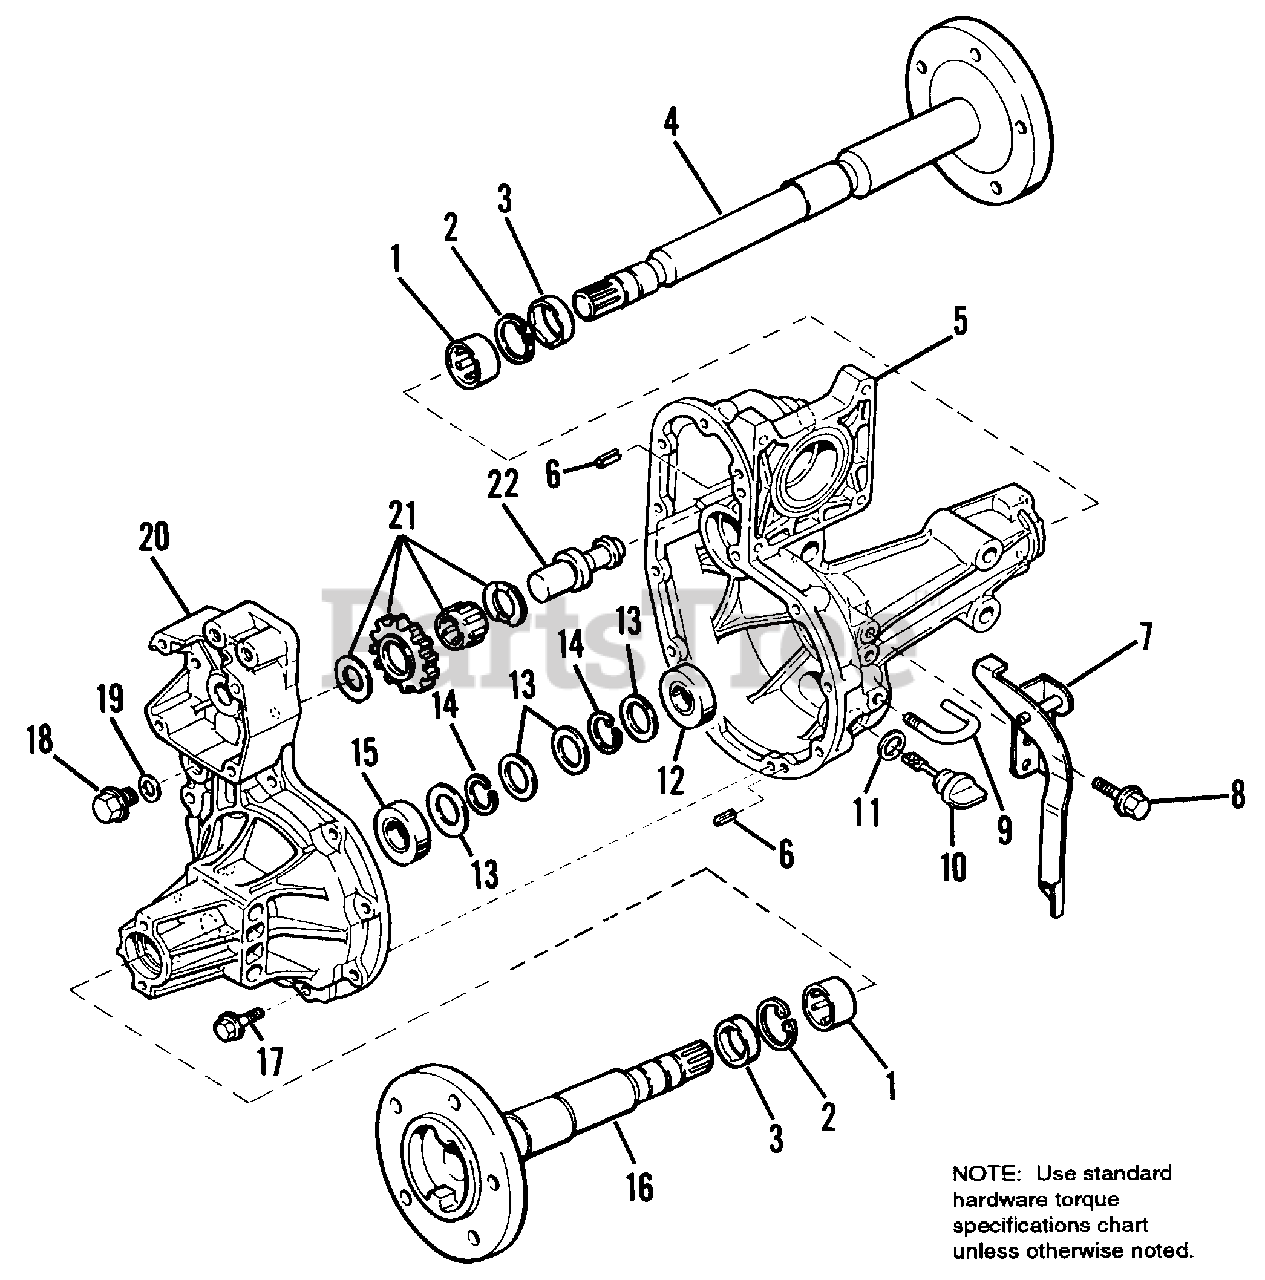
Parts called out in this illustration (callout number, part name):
1	BEARING, Needle
4	SHAFT, Axle, Right
5	HOUSING, Transaxle, Right
7	LEVER ASSY., Range
8	SCREW, Taptite
16	SHAFT, Axle, Left
17	SCREW, Taptite
20	HOUSING, Transaxle, Left
21	GEAR SET, Idle
22	SHAFT, Idle
